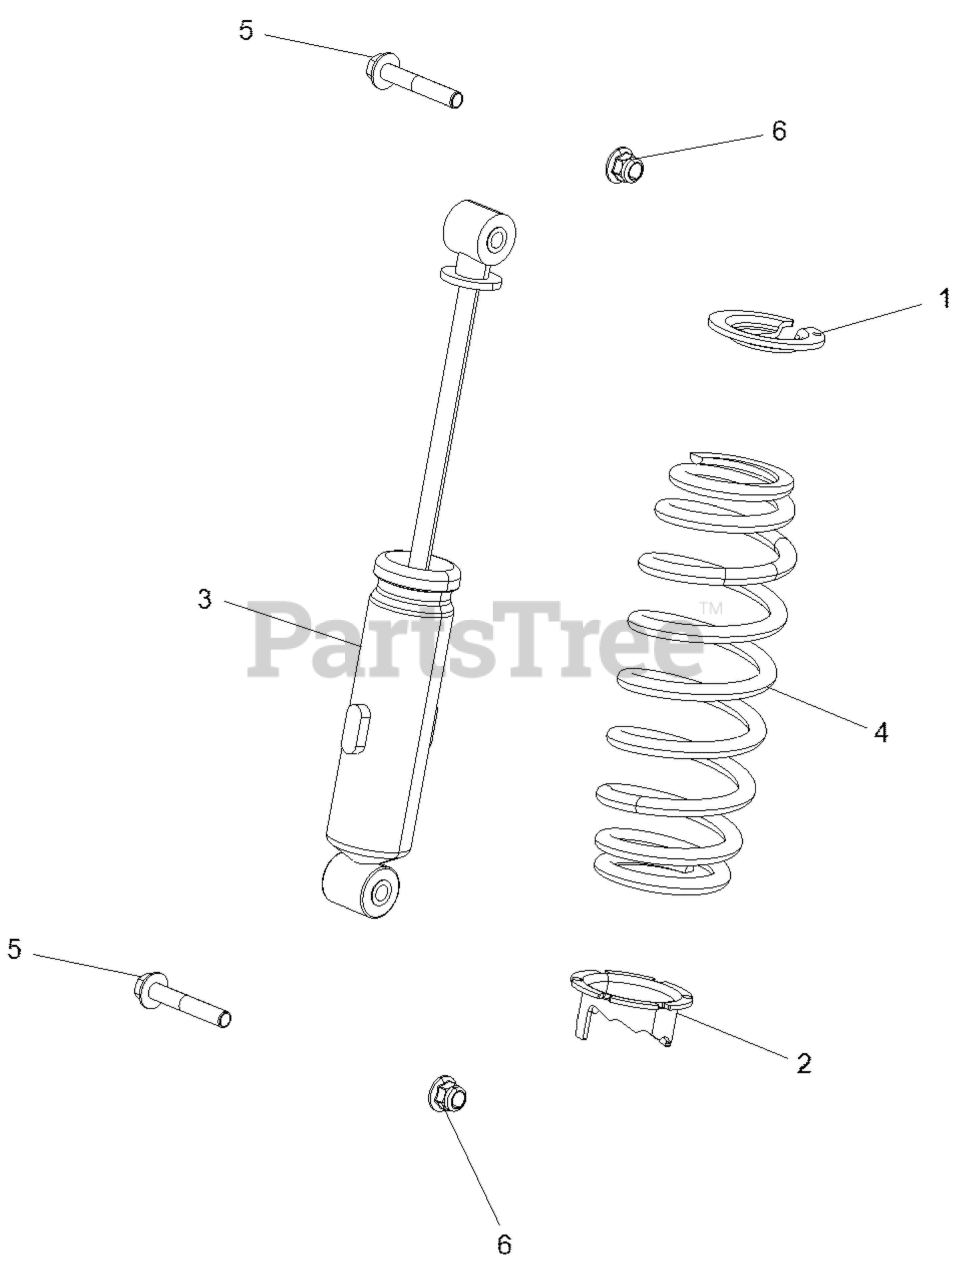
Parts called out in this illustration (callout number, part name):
1	RETAINER-SPRING,STEEL
2	CAM-ADJUSTING,SPRING,STEEL
3	SHOCK-FRONT
4	SPRING, FRONT, MATTE BLACK
5	SCR-HXFL-M10X1.5X65 10.9 RIE
6	NUT-M10X1.5 HFN NYLOC ZOD
